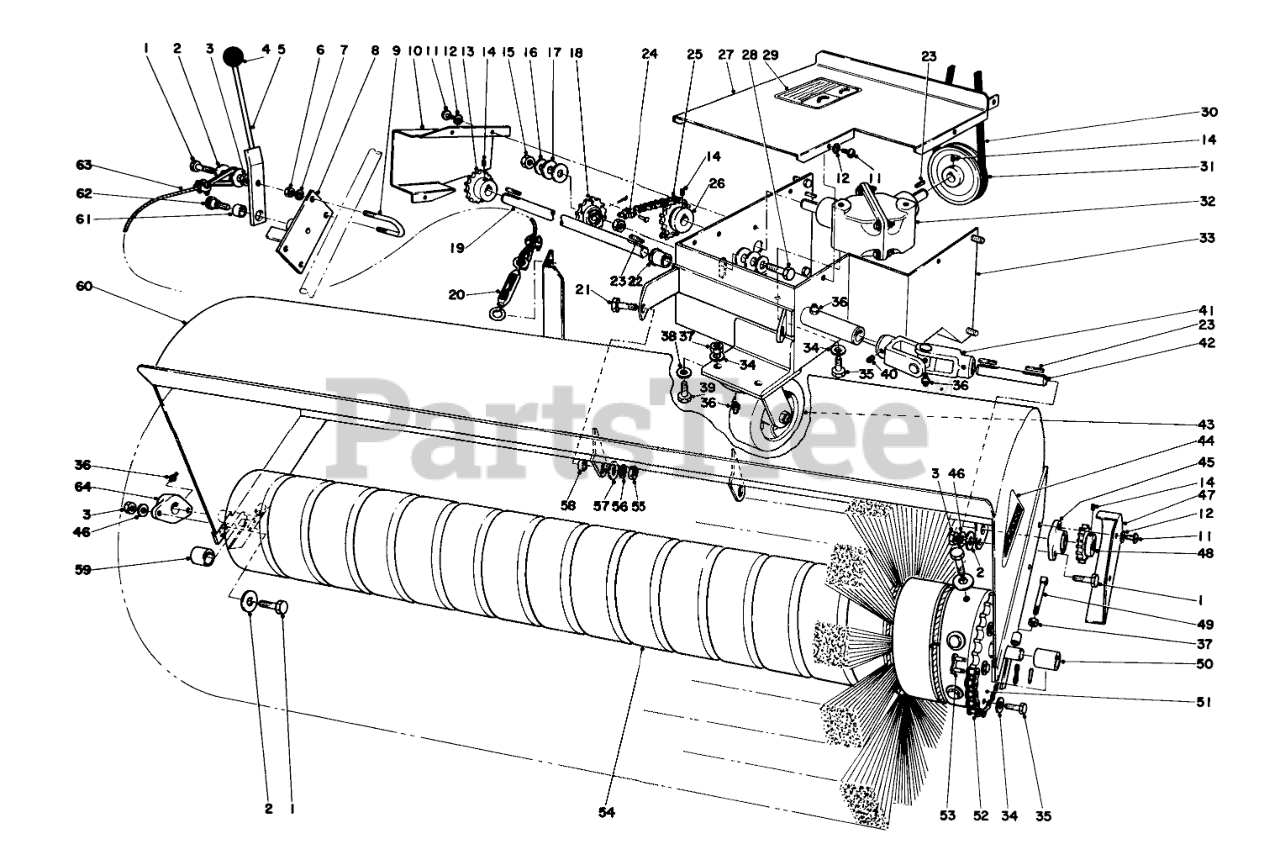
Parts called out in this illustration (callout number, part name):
1	SCREW-HH
2	WASHER-FLAT
3	NUT-HEX
4	Lift Handle Knob
5	Lift Handle
6	NUT-HEX
7	WASHER-LOCK
8	Lift Handle Plate
9	U-Bolt
10	Chain Guard
11	Truss Head Machine Screw
12	WASHER-LOCK/EXT
13	Jackshaft Sprocket
14	SCREW-HSH
15	NUT-JAM
16	RAIL-REAR SHIFT
17	WASHER-FLAT
18	Idler Sprocket
19	Jackshaft Long
20	Turnbuckle
21	SCREW-HH
22	Jackshaft Bushing
24	Offset Link
25	Roller Chain
26	Gear Box Sprocket
27	Mounting Frame Cover
28	Capscrew
29	Brush Adjustment Decal
30	V-Belt
31	Gear Box Sheave
32	Gear Box Assembly
33	Mounting Frame
34	WASHER-LOCK
35	SCREW-HH
36	FITTING-GREASE
37	NUT-HEX
38	WASHER-FLAT
39	SCREW-HH
40	SCREW-SET, HSH
41	Universal Joint Assembly
42	Jackshaft Short
43	Caster Assembly
44	Decal
45	Bearing
46	WASHER-LOCK
47	Chain Guard
48	Gear Box Sprocket
49	Set Screw
50	Brush Shaft Spacer Long
51	Brush Drive Sprocket
52	Roller Chain
53	Connector Link
54	Brush Assembly
55	NUT-HH
56	WASHER-LOCK
57	WASHER-FLAT
58	Pivot Collar
59	Brush Shaft Spacer Short
60	Broom Frame
61	Lift Handle Bearing
62	Shoulder Bolt
63	Lift Cable Assembly(Incl. Ref. No. 20)
64	Brush Shaft Bearing
